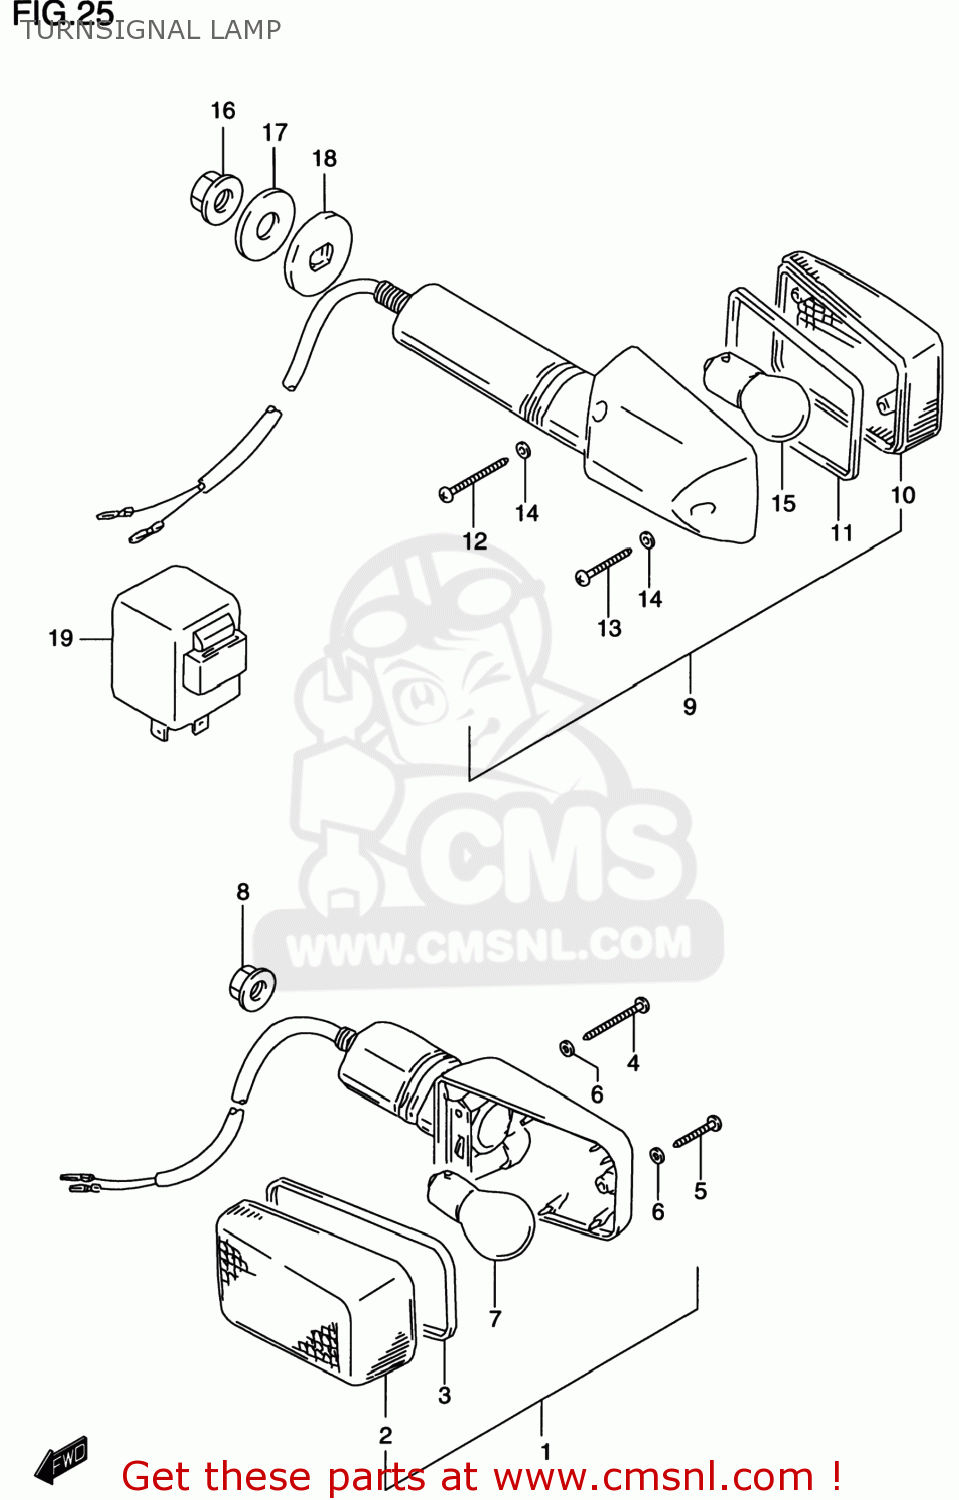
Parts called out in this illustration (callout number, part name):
1	LAMP ASSY,FR TURN SIGNAL
2	LENS
3	GASKET (NAS)
4	SCREW(3X30)
5	SCREW
6	GASKET (NAS)
7	BULB(12V21W)
8	NUT
9	LAMP ASSY,FR TURN SIGNAL
10	LENS
11	GASKET (NAS)
12	SCREW(3X30)
13	SCREW
14	GASKET (NAS)
15	BULB(12V21W)
16	NUT
17	WASHER(10.5X30X2.3)
18	SPACER,RR TURNSIGNAL
19	RELAY ASSY
